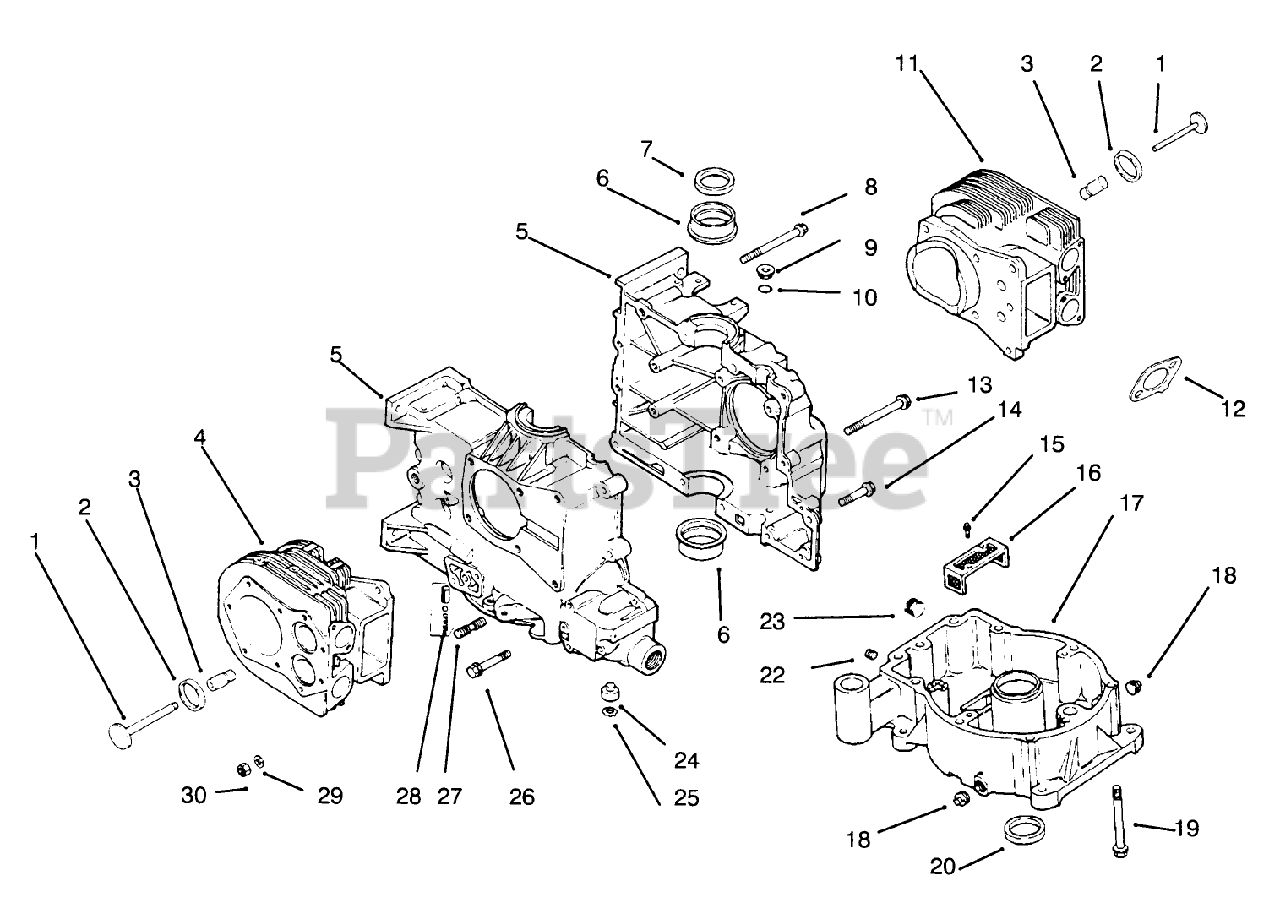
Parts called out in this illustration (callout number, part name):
1	Valve-Exhaust (Ref)
2	Inset-Valve Seat
3	Guide-Valve
4	Kit-#2 Cylinder Barrel (Incl. Ref. #4-6)
5	Crankcase (Ref. Short Block)
6	Bearing-Sleeve
7	Seal-ReAR Oil
8	Screw-Hex Flange
11	Kit-#1 Cylinder Barrel (Incl. Ref. #4-6)
12	Gasket Exhaust
13	Screw-Hex Flange
14	Screw-Hex Flange
15	Screw
16	Filter Oil Pickup
17	Pan-Oil
19	Screw-Hex Washer Hd.
20	Seal-ReAR Oil
22	Plug-Hex Countersunk
24	Shaft-Governor
25	Ring-Retaining
26	Screw-Hex Flange
28	Kit-Oil Relief
29	Washer-Flat
